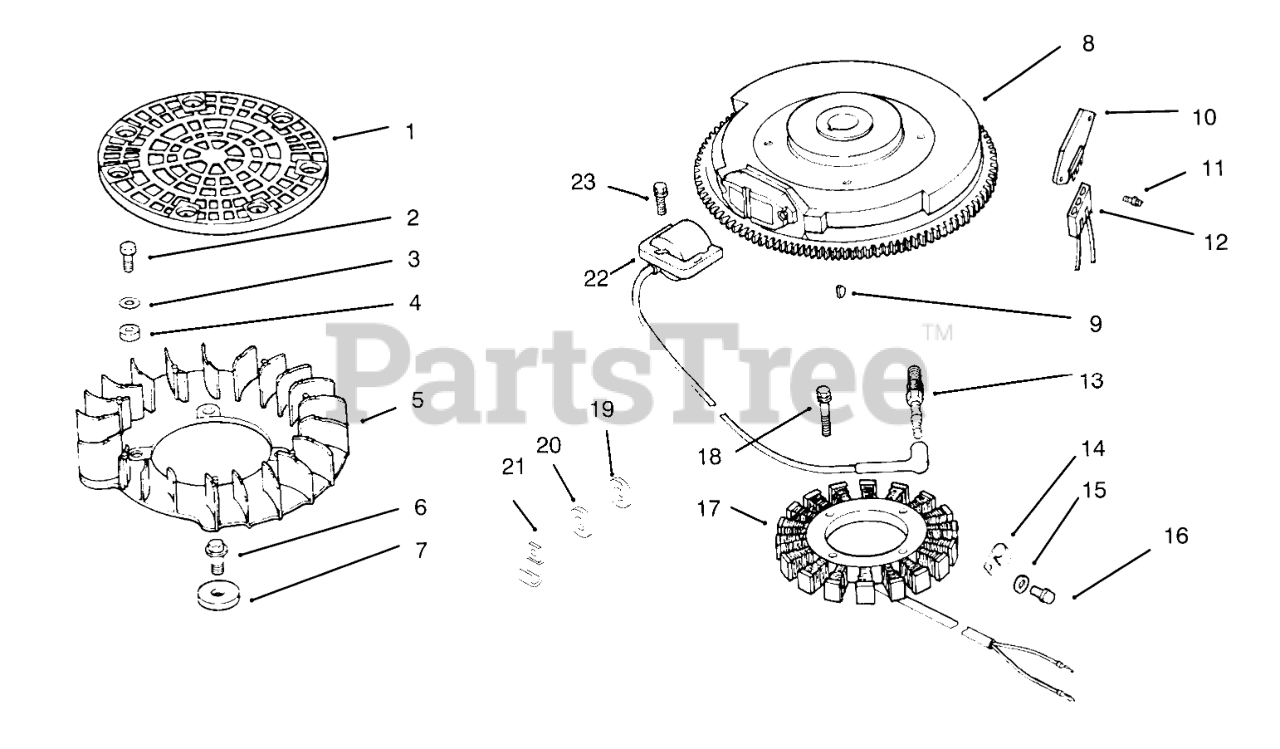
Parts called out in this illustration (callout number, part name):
1	Screen-Grass (Only On: 72103)
2	Screw M4x0.7x24 (Only On: 72103)
3	Washer-Flat (Only On: 72103)
4	Spacer-Fan (Only On: 72103)
5	Fan (Only On: 72103)
6	Screw M6x1.0x16 (Only On: 72103)
7	Spacer-Fan (Only On: 72103)
8	Flywheel ASM (Only On: 72103)
9	Key (Only On: 72103)
10	Rectifier-Regulator (Only On: 72103)
11	Screw-Phillips (Only On: 72103)
12	Connector-Regulator (Only On: 72103)
13	Spark Plug (Only On: 72103)
14	Clip-Stator Harness (Only On: 72103)
15	Washer-Flywheel Screw (Only On: 72103)
16	Screw-Flywheel Mounting (Only On: 72103)
17	Stator-15 Amp (Only On: 72103)
18	Screw M5x0.8x25 (Only On: 72103)
19	Washer-Flat (Only On: 72103)
20	Washer-Flat (Only On: 72103)
21	Clip-Cable (Only On: 72103)
22	Module-Ignition (Only On: 72103)
23	Screw M5x0.8x20 (Only On: 72103)
